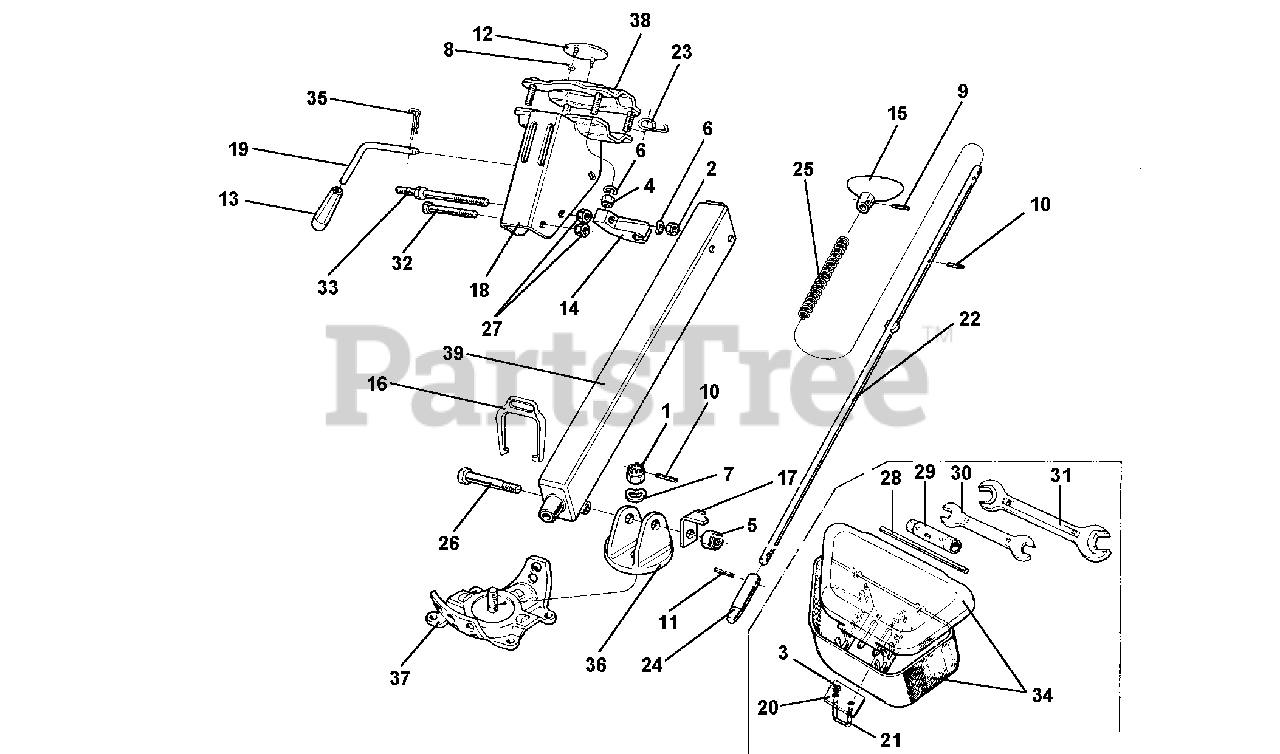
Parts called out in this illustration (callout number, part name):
1	NUT, HEX INT M12 UNI 5593 6S
3	NUT, SELF LOCKING M6
4	NUT, SELF LOCKING M8
5	NUT, SELF LOCKING M12
6	WASHER, LOCK 8.4
7	WASHER, LOCK 13
8	WASHER, LOCK FOR PINS
9	LOCKING PIN 4 X 20 SPIRAL
10	PIN, LOCKING SW 3 X 22 SPIRAL
11	LOCKING PIN SPIRAL
14	SUPPORT CONTROL ROD CUT
16	PASSAGE FOR SHEATH
17	LOCKING PLATE
19	LEVER FOR SECTOR
23	SHEATH HOOK
26	SCREW SPECIAL M12 X 70
27	BEVEL NUT M8
28	PARALLEL PIN D 7 X 130
29	TUBE KEY 10 - 13
30	OPEN KEY 13 - 17
31	OPEN KEY 19 - 22
32	SCREW STEERING COLUMN M8X58
33	SCREW STEERING COLUMN M8X118
34	NEUTRAL TOOL BOX
37	CAP WITH HOLE D. 13
39	HANDLEBAR STEERING COLUMN
